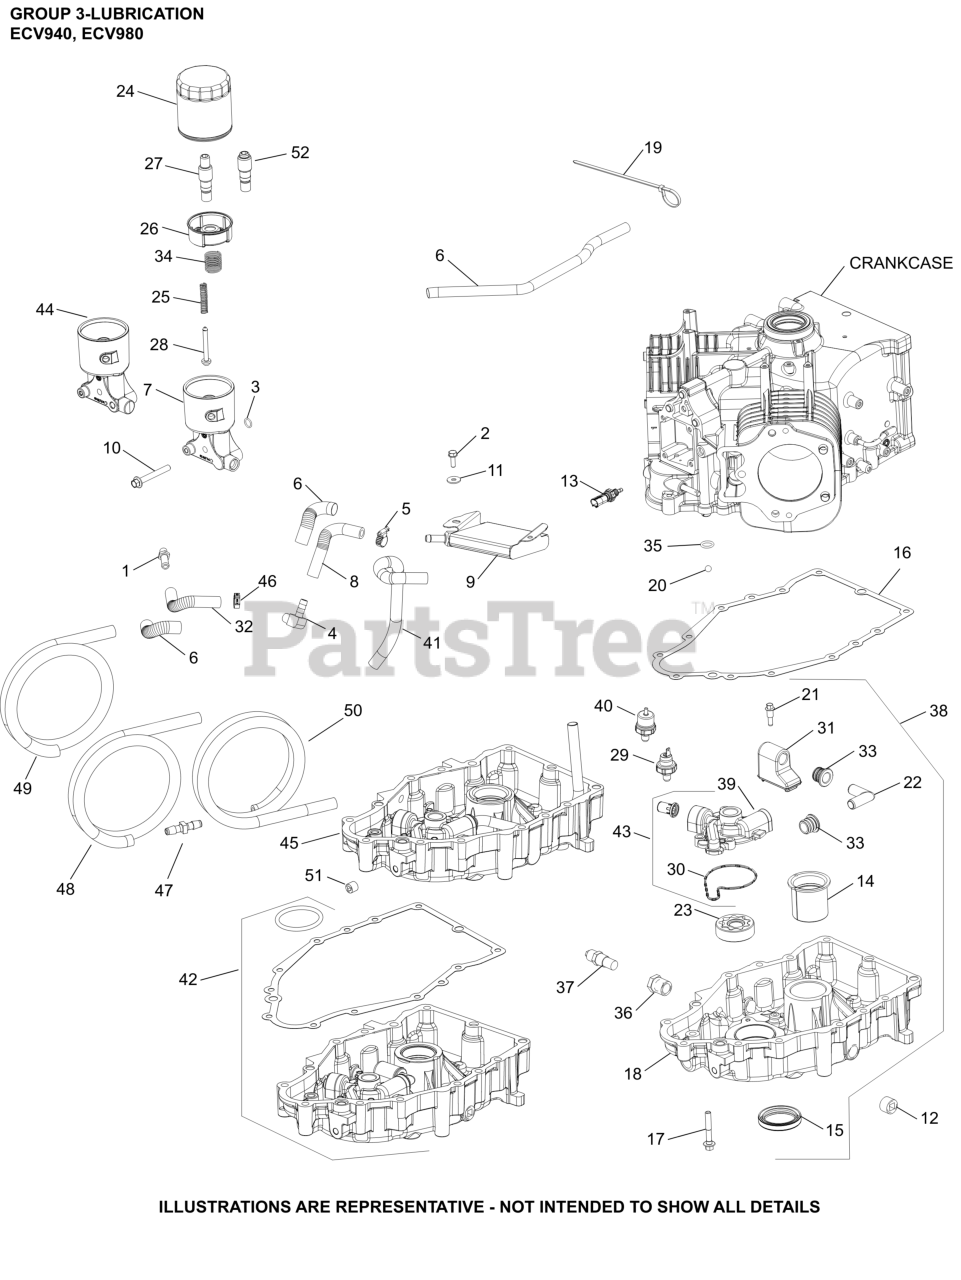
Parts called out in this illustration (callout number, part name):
1	FITTING, HOSE TO PIPE
3	O-RING, OIL PICK-UP
6	SLEEVE, ANTI ABRASION-USE 25 431 12-S
10	SCREW, FLG M8X1.25X60
12	PLUG, PIPE 1/2 NPTF SQ CTSK
13	SENSOR, TEMPERATURE
15	SEAL, OIL PTO SIDE, BROWN
16	GASKET, OIL PAN
17	SCREW, HEX FLANGE
19	TIE, CABLE
20	KIT, CHECK BALL
21	SCREW, SHD THD FRM M6X.0X6.5
22	TUBE, OIL PICK-UP
23	PUMP ASSEMBLY, OIL/GEROTOR
25	SPRING, OIL FILTER VALVE
26	CUP, OIL FILTER ASSEMBLY
28	VALVE, OIL FILTER
29	SWITCH, OIL PRESSURE
30	O-RING, OIL PUMP HOUSING
31	HOUSING, OIL PICK-UP ASSEMBLY
33	SEAL, PICK-UP TUBE
34	SPRING, OIL FILTER CUP
38	KIT, OIL PAN
44	HOUSING, VERTICAL OIL FILTER - MACHINED
46	CLAMP, HOSE OETIKER
47	FITTING, BREATHER
48	HOSE, OIL COOLER
49	SLEEVE, ANTI ABRASION
50	HOSE, OIL COOLER
52	NIPPLE, OIL FILTER ASSEMBLY
NI	OIL FILTER
NI	SCREW, HEX FLANGE M6 X 1
NI	HOUSING, OIL PUMP MACH-USE 62 081 38-S
